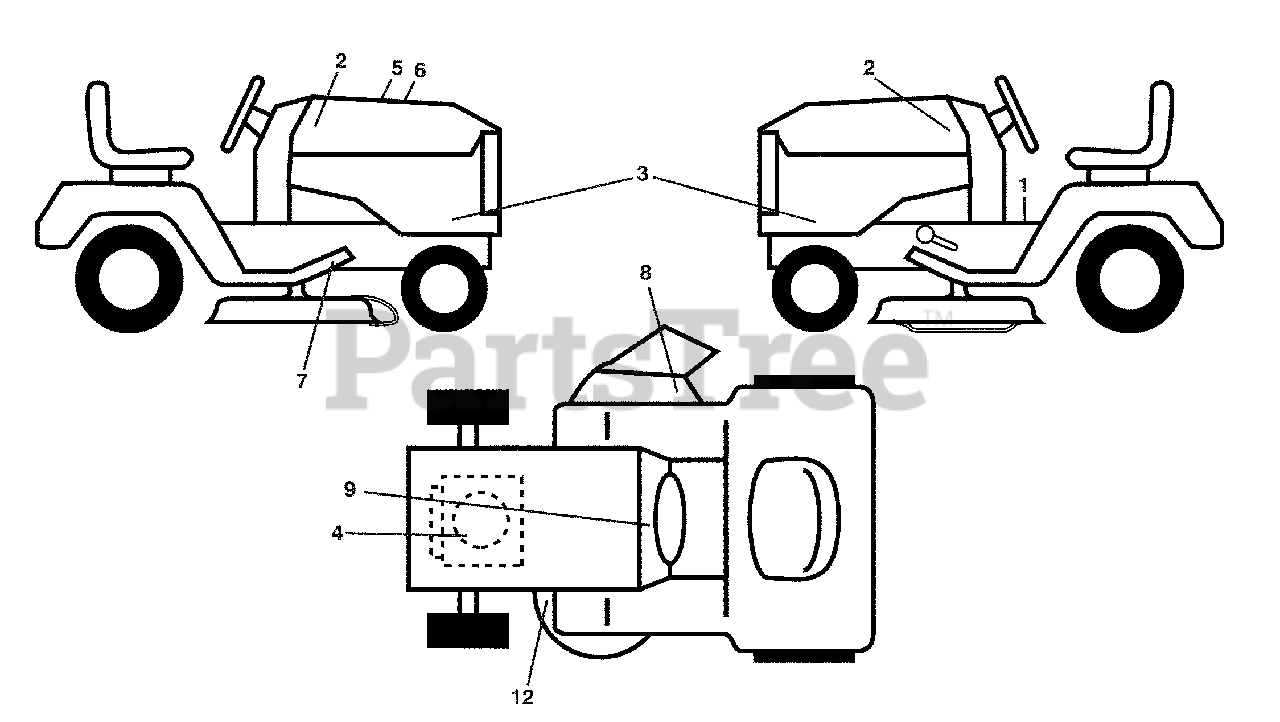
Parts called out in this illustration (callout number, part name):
1	Decal, Operators
2	Decal, Hood
3	Decal, Emblem Panel SD
4	Decal, Engine
5	Decal, Customer Respons.
6	Decal, Replacement
7	Decal, Pedal
8	Decal, Mower Warn Keep Hand Away
9	Decal, Battery Dnge/Poi
12	Decal, Mower V-Belt Schematic
